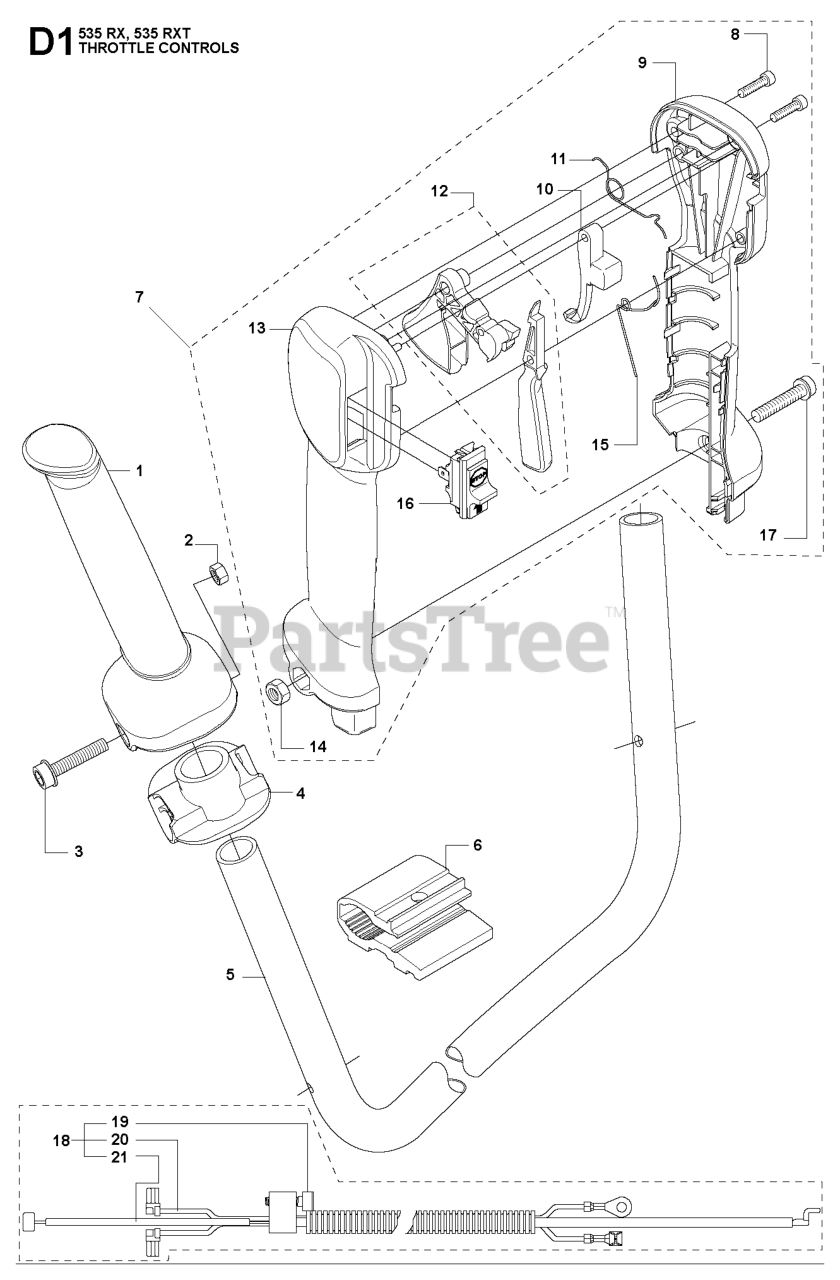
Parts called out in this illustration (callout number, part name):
6	CLAMP
7	HANDLE SYSTEM ASSY
9	HANDLE
10	LOCKOUT STARTER THROTTLE
12	THROTTLE CONTROL
13	HANDLE HALF LEFT
13	HANDLE
16	STOP BUTTON
17	SCREW
18	WIRING KIT COMPLETE
20	SHORT CIRCUIT CABLE
21	THROTTLE WIRE
